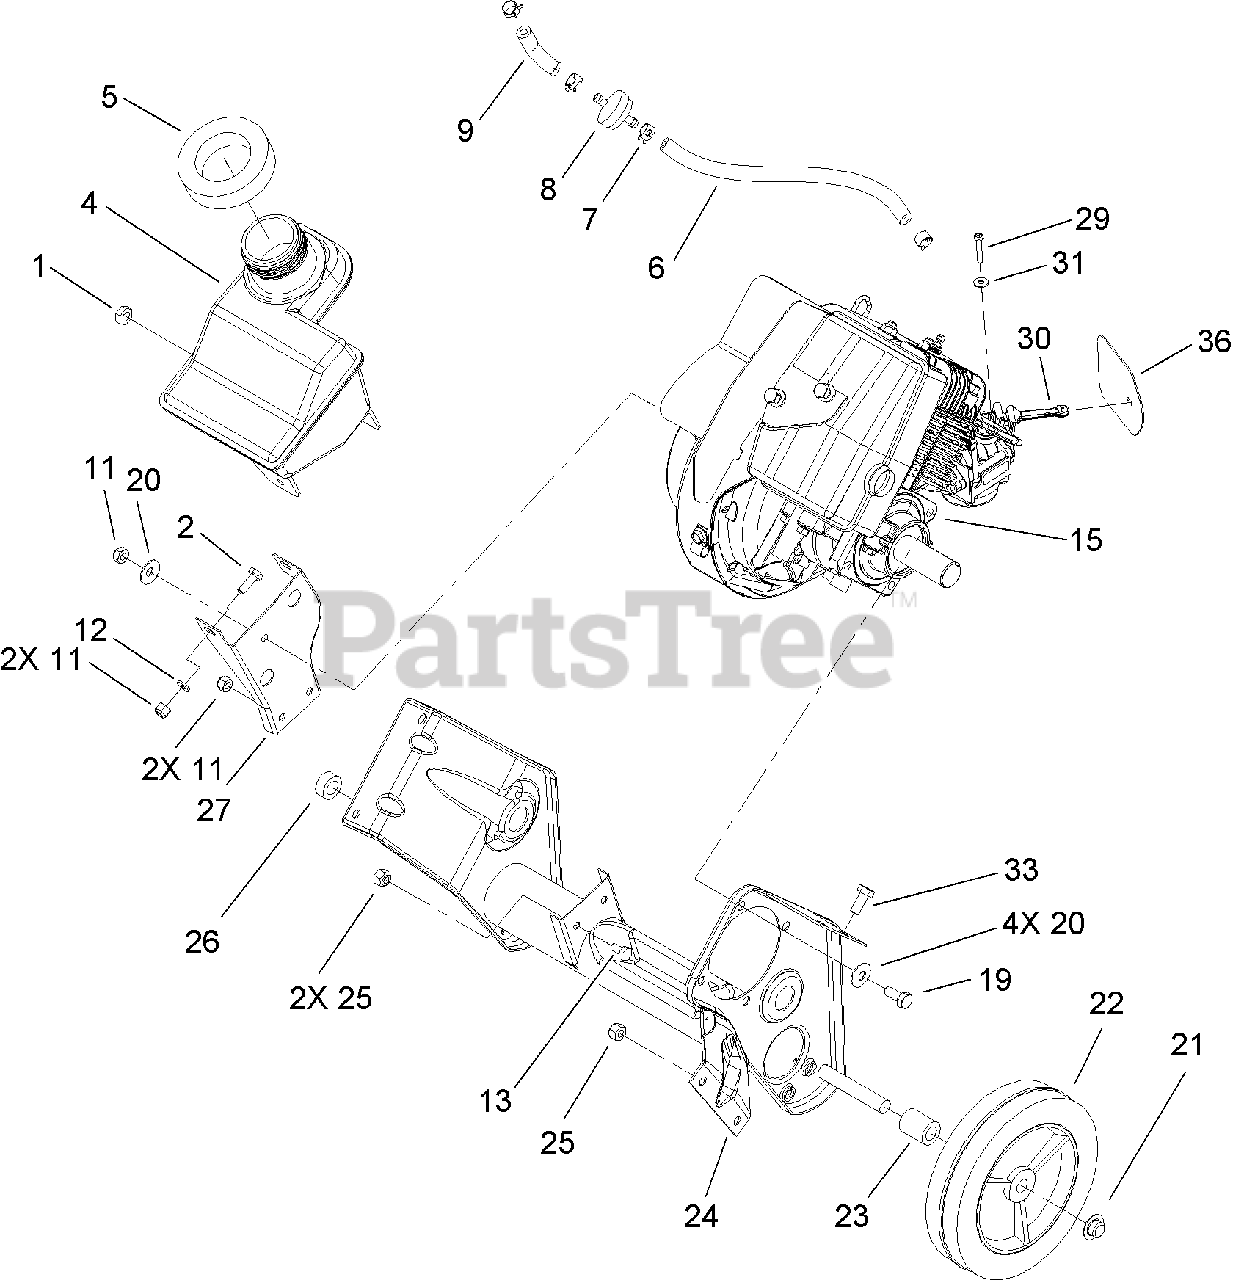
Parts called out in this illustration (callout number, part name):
1	NUT-LOCK, CONE
2	SCREW-HH
5	SEAL-FOAM
6	LINE-FUEL
8	FILTER-FUEL
9	HOSE-FUEL
11	NUT-LOCK, NI
12	WASHER-FLAT
13	SCREW-HH
15	Engine ASM
19	SCREW-HH
20	WASHER-BELLEVILLE
23	SPACER-WHEEL
25	NUT-LOCK, NI
26	SPACER-WHEEL
27	BRACKET-SUPPORT, RECOIL
29	SCREW-PPH, PLASTITE
30	LEVER-CHOKE
31	WASHER-FLAT
33	SCREW-HH
36	SHIELD-HOLE, CHOKE
